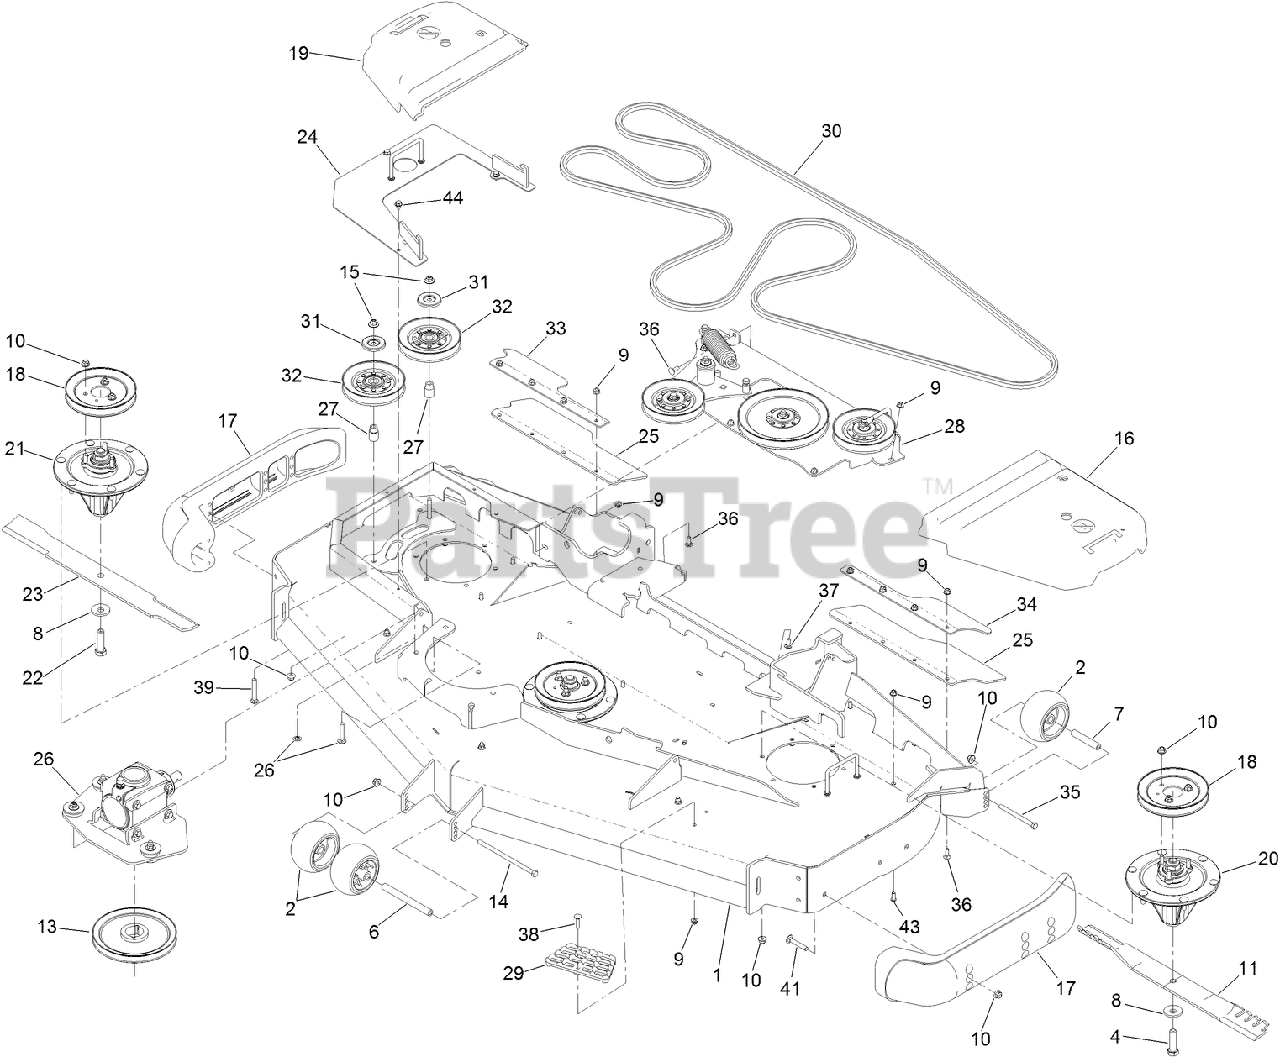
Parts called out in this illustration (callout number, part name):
1	DECK DECAL ASM
2	ROLLER-SCALP, ANTI
4	SCREW-BLADE
6	SPACER-WHEEL
7	TUBE-SPANNER
8	WASHER-BLADE BOLT, HEAVY
9	NUT-HF, NI
10	NUT-HF, NI
11	BLADE-ATOMIC, 24.5IN
13	PULLEY
14	SCREW-HH
15	NUT-FLANGE, NI
16	COVER-BELT, LH
17	SKID-BUMPER, DECK
18	PULLEY
19	COVER-BELT, RH
20	SPINDLE ASM
21	LH SPINDLE ASM
22	SCREW-BLADE, LH
23	BLADE-ROTARY, 24.5IN (LOW FLOW)
24	COVER-REVERSE DRIVE
25	GUARD-TIRE
26	GEARBOX ASM
27	STANDOFF-IDLER
28	IDLER MOUNT ASM
29	STEP-DECK
30	BELT-BB
31	SHIELD-DUST
32	IDLER V
33	SUPPORT-FLAP, OUTER (RH)
34	SUPPORT-FLAP, OUTER (LH)
35	SCREW-HH
36	SCREW-CARR
37	SCREW-CARR
38	SCREW-CARR
39	SCREW-CARR
41	SCREW-HH
43	SCREW-HSBH
44	SCREW
